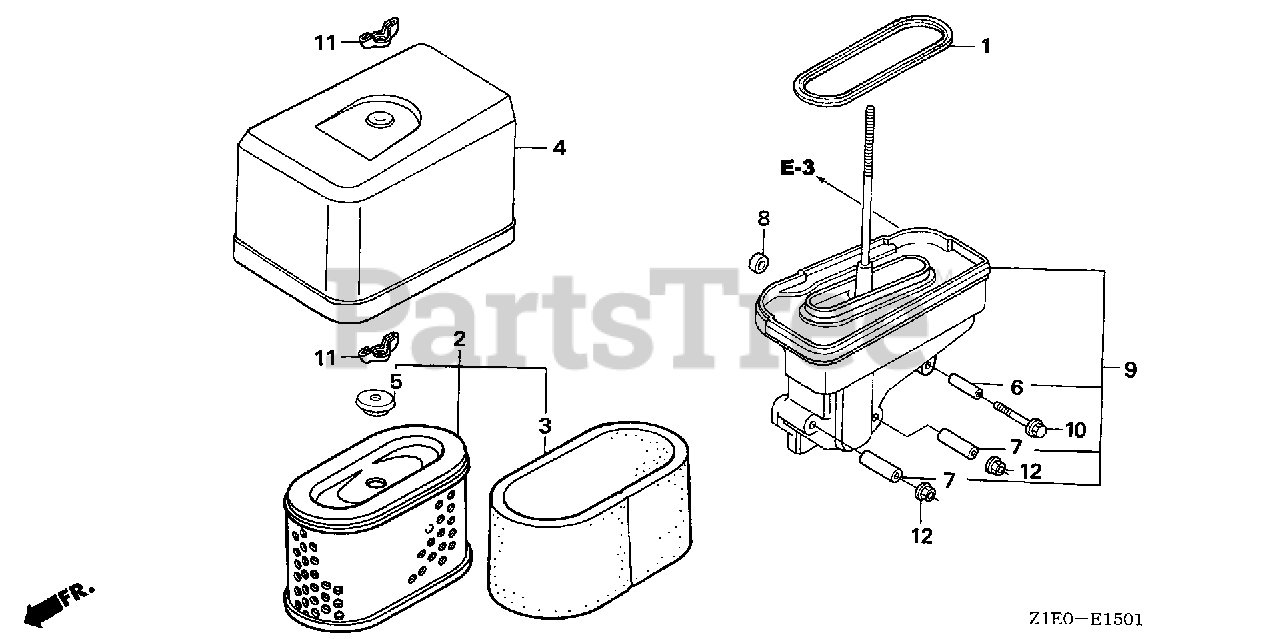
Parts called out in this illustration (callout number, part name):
1	GASKET, ELBOW
2	ELEMENT, AIR CLEANER (METAL BASE)
3	FILTER (OUTER)
4	COVER, AIR CLEANER (DUAL)
5	GROMMET, AIR CLEANER
6	COLLAR, AIR CLEANER Use up to Engine SN 1786084.
7	COLLAR, AIR CLEANER
8	SPACER, AIR CLEANER ELBOW
9	ELBOW, AIR CLEANER
10	BOLT, FLANGE (6X35)
11	WINGNUT, TOOL BOX SETTING
12	NUT, FLANGE (6MM)
